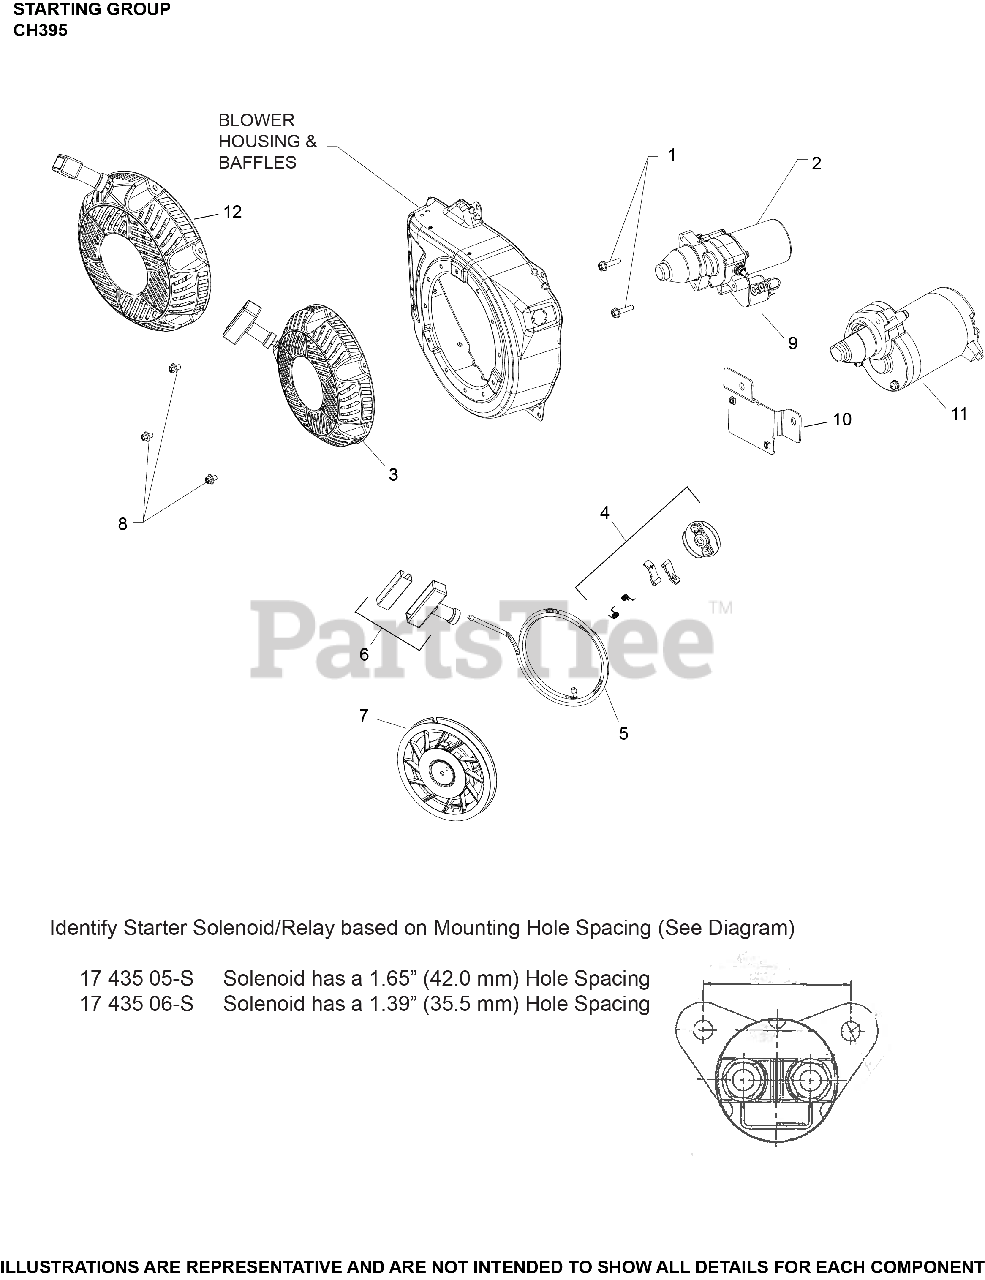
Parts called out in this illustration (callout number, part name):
2	STARTER ASSEMBLY
3	RETRACTABLE STARTER ASSEMBLY
4	KIT, PAWL REPAIR
5	KIT, ROPE
6	KIT, HANDLE
7	PULLEY, RECOIL
